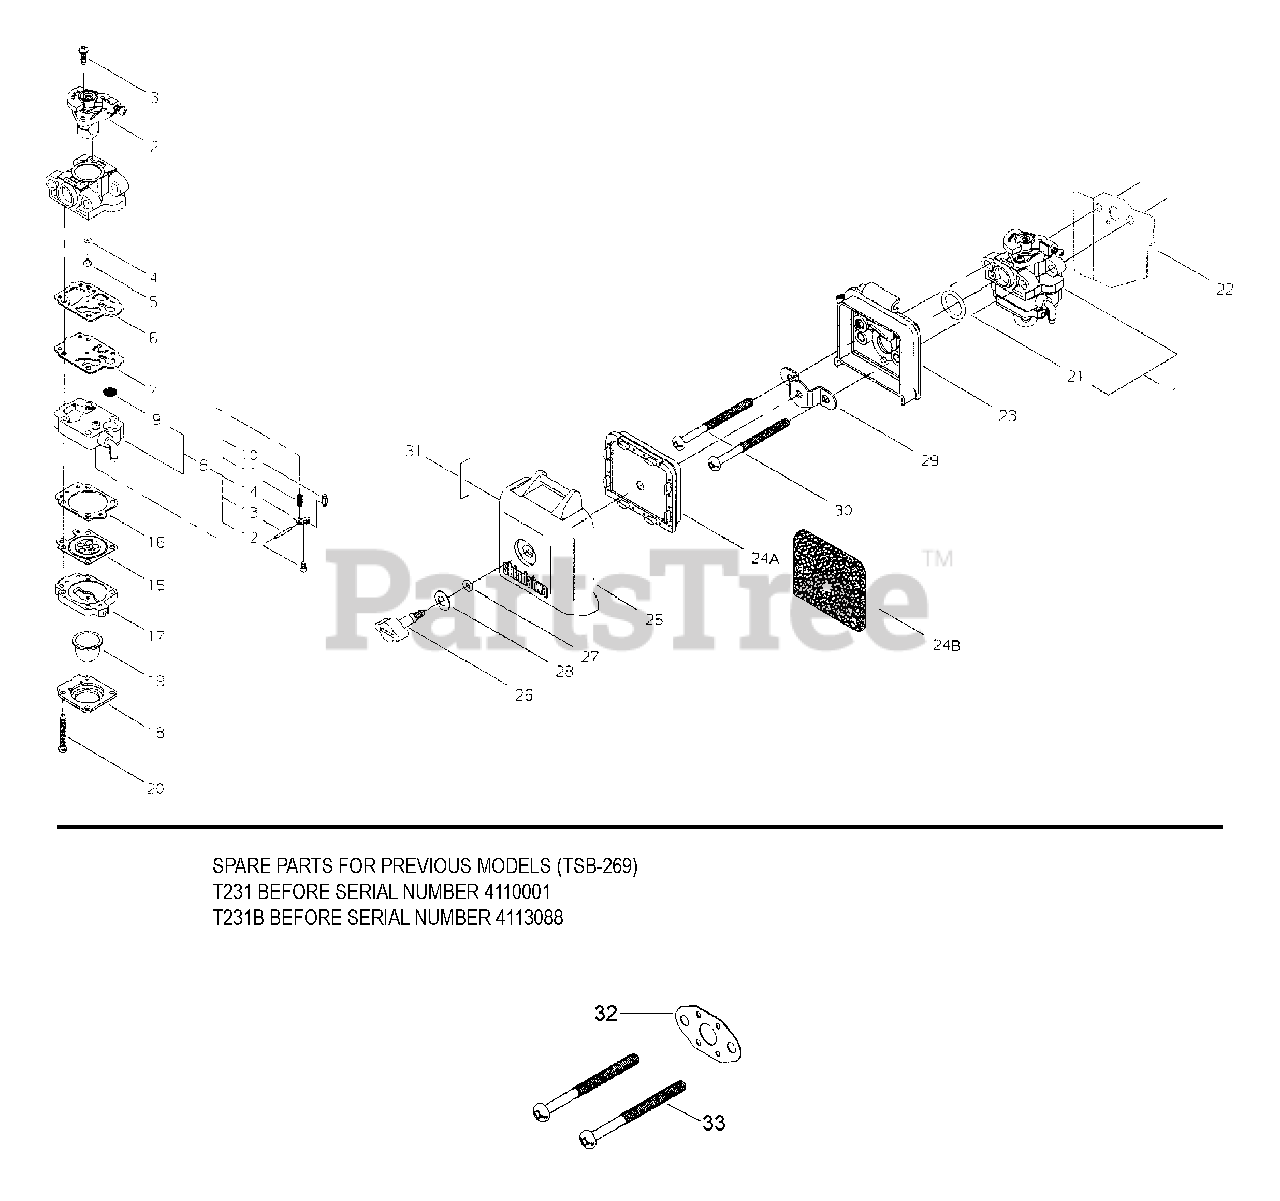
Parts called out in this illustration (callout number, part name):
1	CARBURETOR
2	VALVE, THROTTLE
3	SCREW
4	O-RING
5	JET, MAIN
6	GASKET, PUMP
7	DIAPHRAGM, PUMP
8	BASE, PURGE
9	STRAINER
10	VALVE, INLET NEEDLE
11	SPRING, METERING LEVER
12	SCREW, METERING LEVER PIN
13	PIN, METERING LEVER
14	LEVER, METERING
15	DIAPHRAGM, METERING
16	GASKET, METERING
17	BASE, PURGE
18	RETAINER, PURGE BULB
19	BULB, PURGE
20	SCREW, PUMP COVER
21	O-RING - 15
22	SHIELD, INTAKE
23	CASE, AIR FILTER
24A	FILTER, AIR - HEAVY DUTY
24B	FILTER, AIR - FOAM
25	COVER, AIR FILTER
26	THUMBSCREW
27	O-RING
28	WASHER - CONICAL
29	PLATE, PREVENT
30	SCREW - 5X60
31	LABEL - CHOKE
32	GASKET
33	SCREW - 5X67
